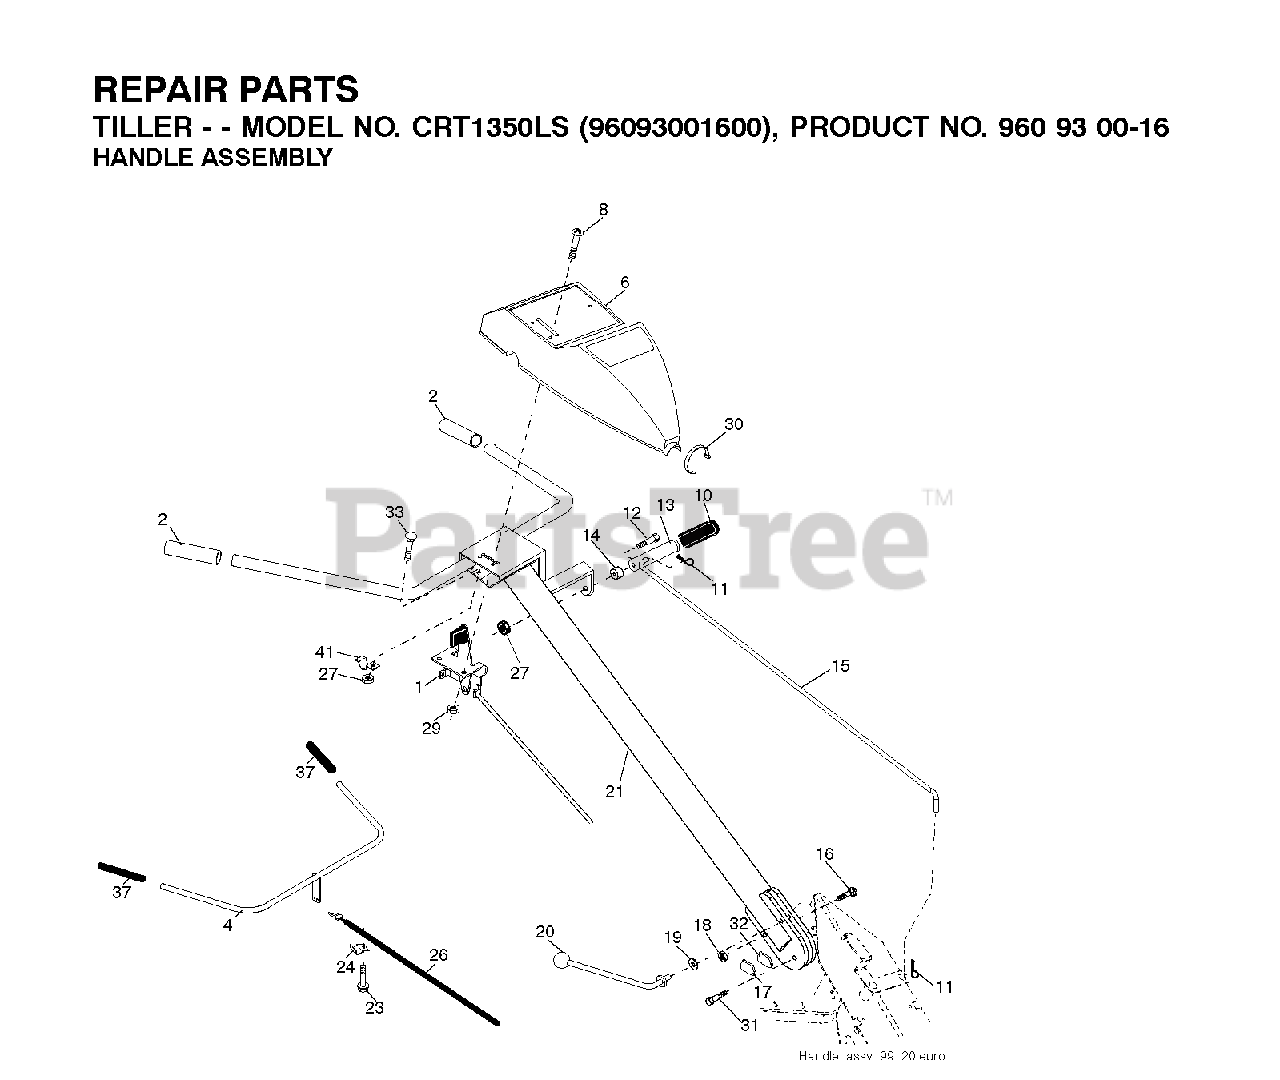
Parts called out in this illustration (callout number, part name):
1	THROTTLE.CONTROL.
2	GRIP.1X5.06
4	CONTROL BAR ASSY
6	RP CONTROL PANEL
8	SCREW.PNHD.10-24
10	GRIP T
11	RETAINER M
12	SHOULDER BOLT ST
13	HANDLE.SHIFT.TILLER
14	GROMMET.RUBBER.CRT.TILLER
15	ROD.SHIFT.YARD PRO.UNIVERSAL.
16	BOLT D
17	LOCK.HANDLE.CRT
19	WASHER CRT
20	LEVER.LOCK.CRT
21	HANDLE.ASM.TILLER.GREY.
23	TAPPING SCREW
24	CONDUIT.CLIP.PLATED
26	CABLE.CLUTCH
27	NUT T
29	NUT **
30	TIE CABLE CRT
31	BOLT.PIVOT
32	LOCK HANDLE
37	GRIP BAR CRT(1)
41	CLAMP.BAR.CRT.BLACK
